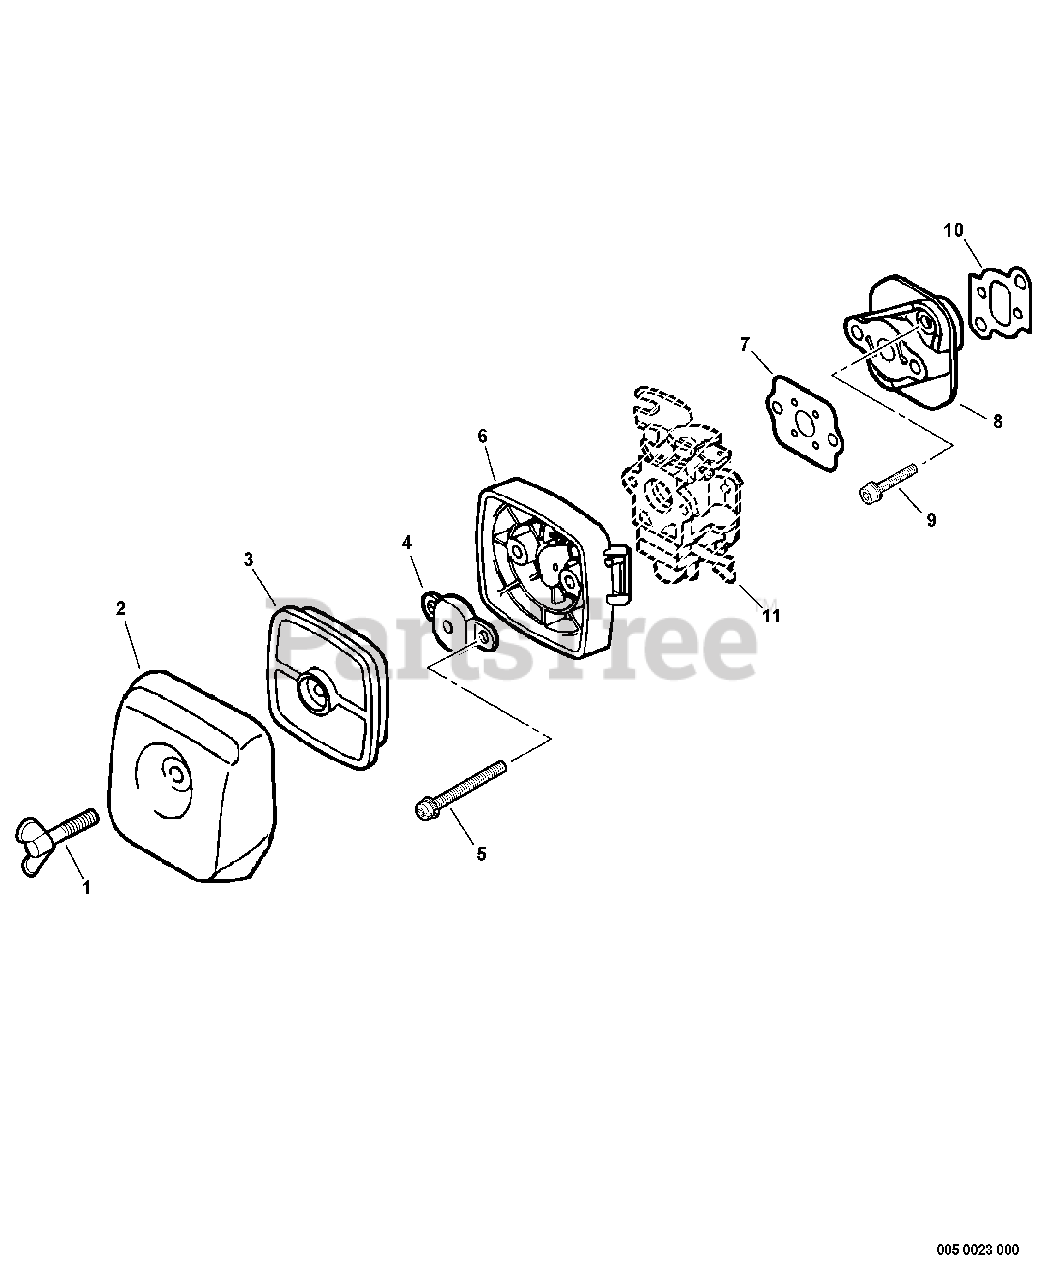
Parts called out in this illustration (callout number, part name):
1	BOLT, WING 5×20
2	COVER, AIR FILTER - GRAY
3	FILTER, AIR - SINGLE LAYER
4	PLATE, PREVENT
5	SCREW 5×60
6	CASE, AIR FILTER - GRAY
7	GASKET, INTAKE
8	INSULATOR, INTAKE
9	BOLT 5×25
10	GASKET, INTAKE
11	CARBURETOR
12	TUNE-UP KIT - REPOWER
13	TUNE-UP KIT - REPOWER
